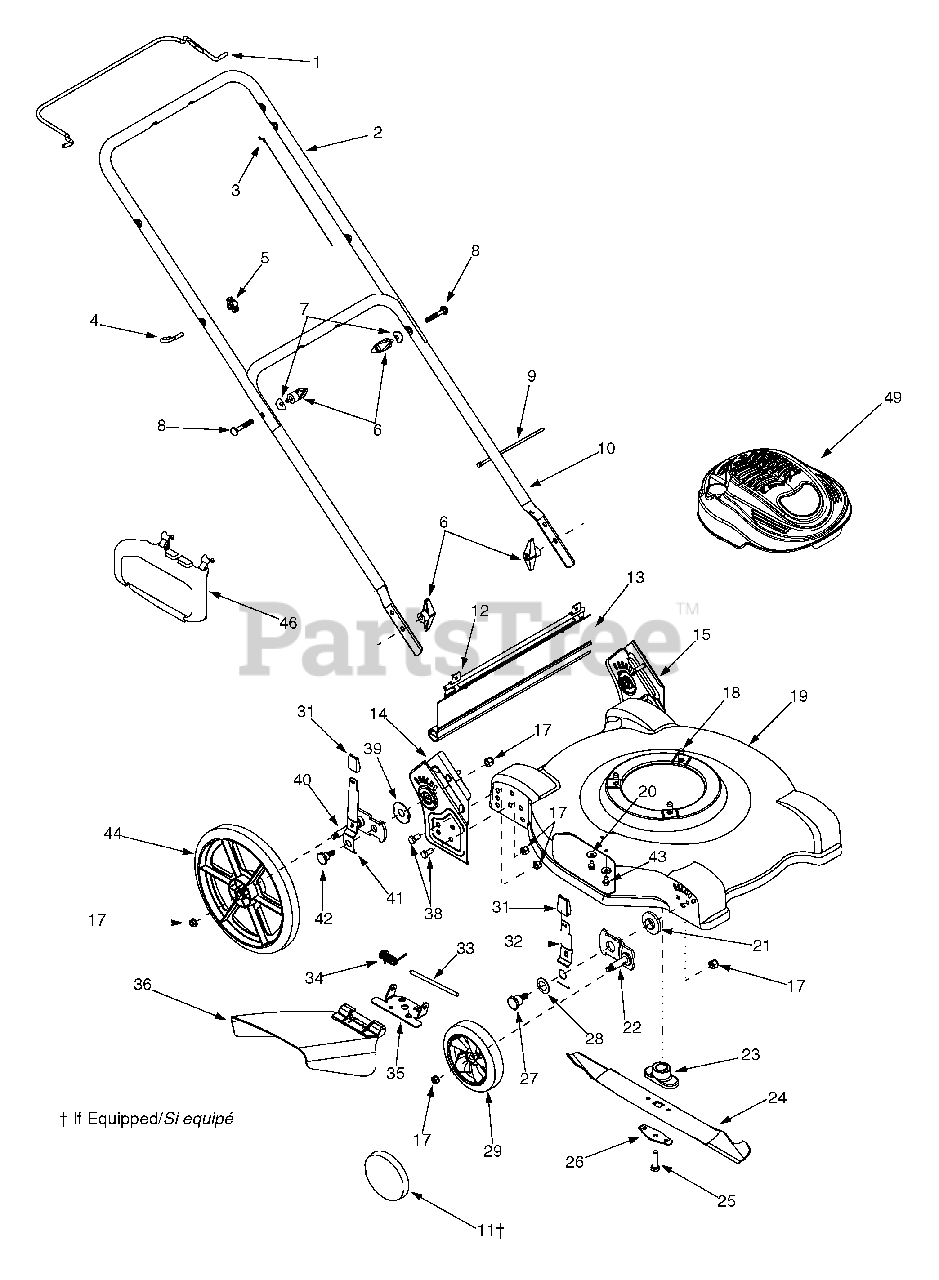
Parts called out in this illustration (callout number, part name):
3	Control Cable 48.25" Lg.
4	Rope Guide Bolt
5	Knob - ERS Guide 1/4-20
6	Handle Knob Assembly
7	Saddle Wash. .320 ID x .937 OD
8	Carriage Bolt 5/16-18 x 2.0
9	Cable Tie
11	Hub Cap Grey Radial
12	Hinge Clip
13	Trail Shield
18	Hex Wash HD Tap Scr 3/8-16 x .88
20	Cupped Washer .265 ID x .75 OD x .062
21	Height Adjuster Bearing
22	Pivot Bar
23	Blade Adapter
24	Mulching Blade 22"
25	Hex Screw 3/8-24 x 1.5" Lg. (Gr. 8)
26	Blade Bell Support
27	Shoulder Screw 3/8-16
28	Cupped Washer .401 ID x .870 OD
29	Wheel Assembly Complete 7 x 1.8
31	Height Adjuster Knob
32	Spring Lever
33	Hinge Pin
34	Torsion Spring
35	Deflector Chute Adapter
36	Side Dis. Chute Ass'y
38	Hex Cap Screw 3/8-16 x .75
39	Thrust Bearing .688 ID x 1.938 OD
40	RH Rear Pivot Arm Assembly
40	LH Rear Pivot Arm Assembly
41	Rear Spring Lever
42	Shoulder Screw 3/8-16 x .442
43	Hex Wash S-Tapp Scr 1/4-20 x .50
44	Wheel Assembly 12 x 1.8 Bar Grey
46	Mulch Plug
